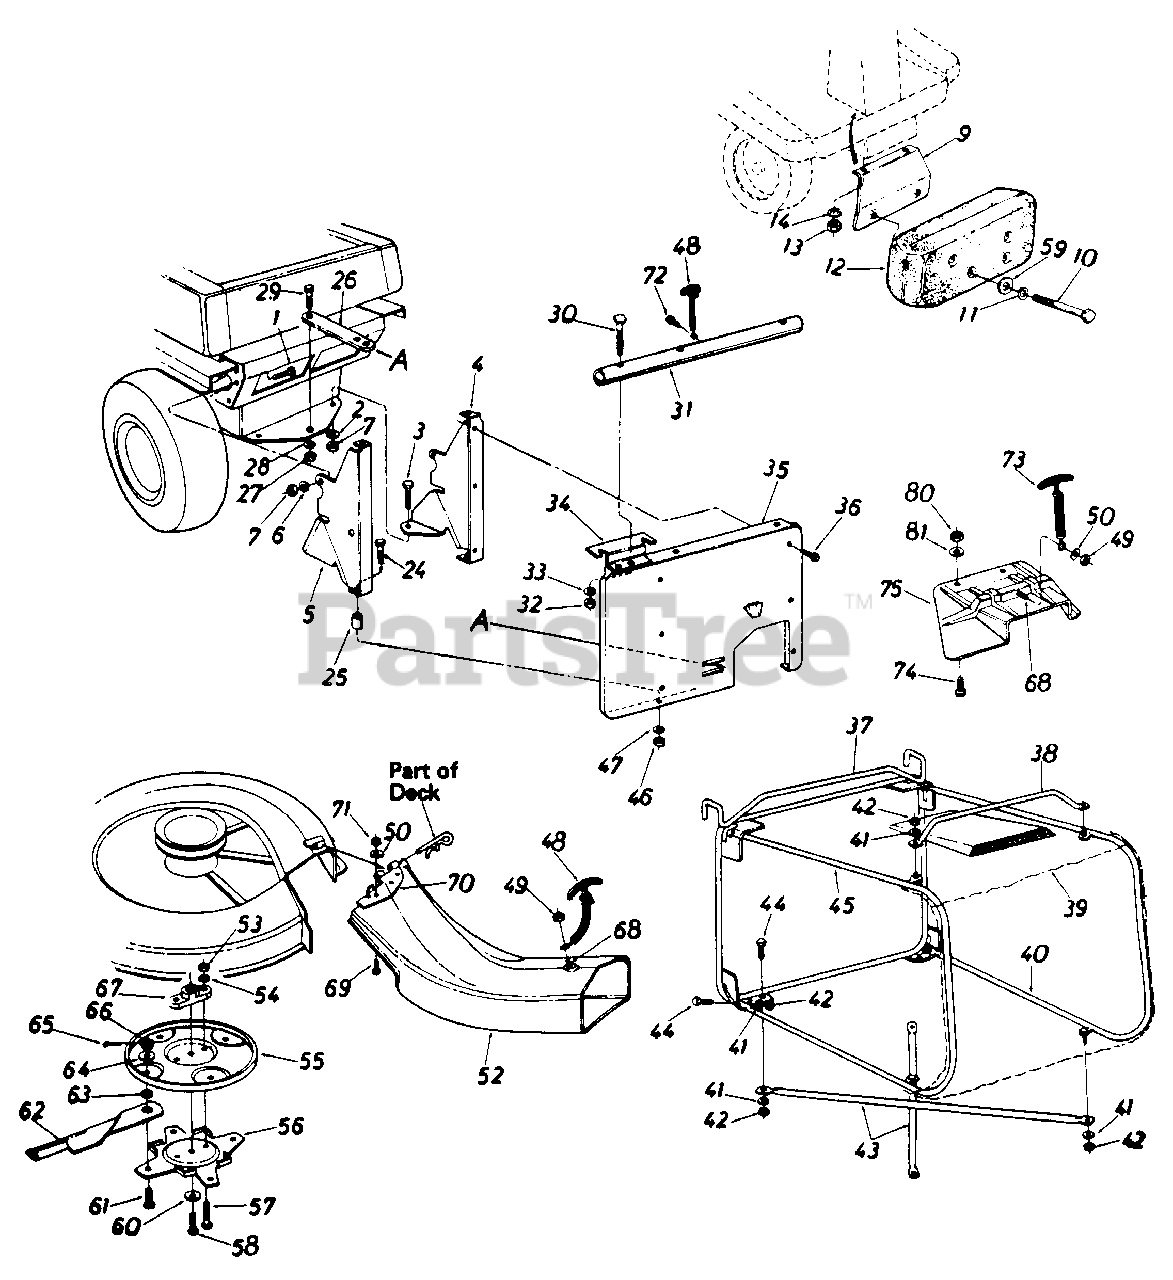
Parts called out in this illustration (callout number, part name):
1	Hex Bolt 5/16-18 x 1.0" Lg.
2	L.-Wash. 5/16" I.D.
3	Hex Bolt 5/16-18 x 1.0" Lg.
4	Catcher Support Brkt - R.H.
5	Catcher Support Brkt - L.H.
6	L.-Wash. 5/16" I.D.
7	Hex Nut 5/16-18 Thd.
9	Counterweight Support Brkt. Ass'y
10	Hex Bolt 3/8-16 x 4.5" Lg.'
11	Belleville Wash. .40" I.D. x .88" 0. D.
12	Counterweight 38 lbs.
13	Hex Nut 5/16-18 Thd.
14	L.-Wash. 5/16" I.D.
24	Hex Bolt 5/16-18 x 1.50" Lg.
25	Spacer .380" I.D. x .47" O.D. x 1.0" Lg.
28	L.-Wash. 1/2" I.D.
29	Hex Bolt 1/2-20 x 1.0" Lg.
30	Curved Carriage Bolt 5/16 18 x 1.75" Lg.
33	L.-Wash. 5/16" I.D.
34	Grass Catcher Support Plate
35	Rear Discharge Panel
36	Hex Wash. Hd. Self Tap. Scr. 1/4-20 x .50" Lg.
37	Grass Catcher Frame Ass'y.
42	Hex L.-Nut 1/2-20 Thd
43	Bottom Cross Brace
44	Hex Bolt 1/4-20 x .62" Lg.
47	L-Wash. 5/16" I.D.
48	Hook Latch Ass'y.
49	Hex L.-Nut I.D. 20 Thd.
50	L-Wash. 1/4" I.D.
52	R.D. Banana Chute Ass'y.
53	Hex Nut 5/16-24 Thd.
54	L. Wash. 5/16" I.D.
55	Upper Blade Disc
58	Hex Bolt 3/8-24 x 1.0" Lg.
59	Fl.-Wash. .39" I.D. x 1.12" O.D.
60	Bell -Wash. 39" I.D. x 1.38"
61	Shld. Bolt. .50" Dia. x .360 Spec.
62	30" Blade Tip
63	Spacer .505" I.D. x .75" O.D. x 1.25" Lg.
64	Fl. Wash. .50" I.D. x 1.25" O.D.
65	Cotter Pin 3/32" Dia. x 1.0" Lg.
66	Hex Slotted Nut 1/2-20 Thd.
67	Blade Adapter
68	Hex Bolt 1/4-20 x .50" Lg.
69	Truss Mach. Scr. 1/4 20 x .50" Lg.
72	Hex AB Tap Scr. 1/4 x .62" Lg.
73	Hook Latch Ass'y. 7" Lg.
74	Truss Mach. Scr. 1/4-20 x 50" Lg.
75	R D Chute Extension
80	Hex L. Nut 1/4-20 Thd.
81	Fl.-Wash. .281" I.D. x .50" O.D. x .063
